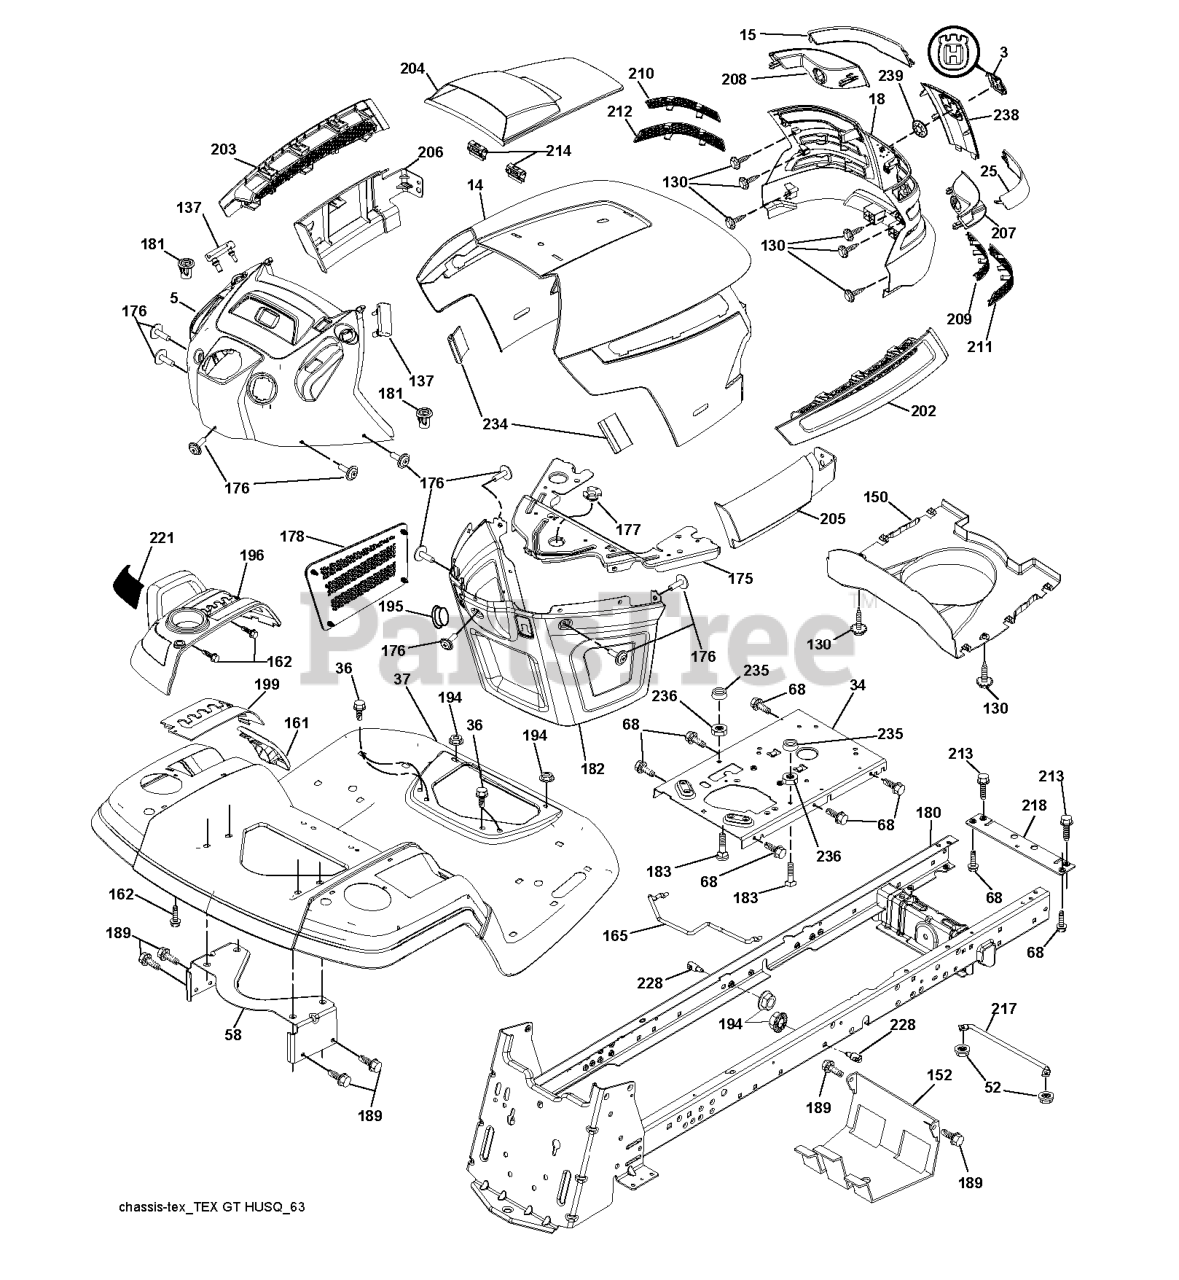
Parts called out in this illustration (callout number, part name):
3	RP LOGO
14	HOOD
15	LENS.LH.TEX.GT.HUSQ.CL
18	GRILL.ASM.HUSQ.TG/CRD.W/TRIM
25	LENS.RH.TEX.GT.HUSQ.CL
34	PLATE.ENGINE.WELDED.CHASSIS
36	SCREW 5/16"
37	FENDER.PNT.TX.GT.CH/FW.ORANGE
52	LOCKNUT
58	BRKT.SUPPORT.FNDR/TANK
68	Screw 5/16-18 x 1/2 Hex, Self Tapping 5/16-18 x 1/2
130	SCREW.#10 X 0.750.BOS
137	BUMPER DASH
150	AIR.DUCT.HOOD.TEX.GT.HUSQ
152	SHIELD.BROWNING.W/TEX
161	CONSOLE.FUEL.WINDOW.HU
162	SCREW.HI-LO.CONSOLE
165	SUPPORT.TANK.REAR.W/TEX
175	PLATE.CROSSMEMBER.HUSQ
176	SCREW.#10-24X5/8.RN.QU
177	BUSHING, STEERING
178	CARGO.ASM.NET.TXGT.W/C
180	CHASSIS.GT.SLOPED.DRAWBAR.
181	BUSHING.MNT.FEND.CRGO.
182	DASH.LOWER.COMMON.12V.ADAPTOR
183	BOLT.5/16-18X1-1/4 FULL THD
189	SCREW
194	NUT LOCK HEX FLANGE 5/16-18
195	PLUG.HOLE.DASH.LOWER.12V.BLK
196	RP CONSOLE.ASM.DECKLFT.W/
199	PLATE.DECK.LIFT.HUSQVARNA.GT
202	VENT.SIDE.HOOD.HUSQ.RH.GREY
203	VENT.SIDE.HOOD.HUSQ.LH.GRAY
204	HOOD VENT
205	SKIRT.HOOD.SIDE.HUSQ.RH.GREY
206	SKIRT.HOOD.SIDE.HUSQ.LH.GREY
207	BEZEL.RH.TEX.GT.HUSQ
208	BEZEL.LH.TEX.GT.HUSQ
209	INSERT.HEX.GRILL.HUSQ.GREY
210	INSERT.HEX.GRILL.HUSQ.
211	INSERT.HEX.GRILL.HUSQ.
212	INSERT.HEX.GRILL.HUSQ.
213	BOLT
214	CLIP.RETAINER.TINNER.
217	ROD.PIVOT.HOOD
218	X-PIECE.HOOD.STOP.NON/
221	REFLECTOR.LH.TEX GT HU
228	STUD.FASTNER.W/ANTI-ROTATE
234	BUMPER.HOOD.TEX.HUSQVARNA
235	SPACER FENDER
236	NUT.CENTERLOCK.5/16-
238	TRIM.HUSQ.TG/CRD.SERVICE
239	NUT PUSH M
